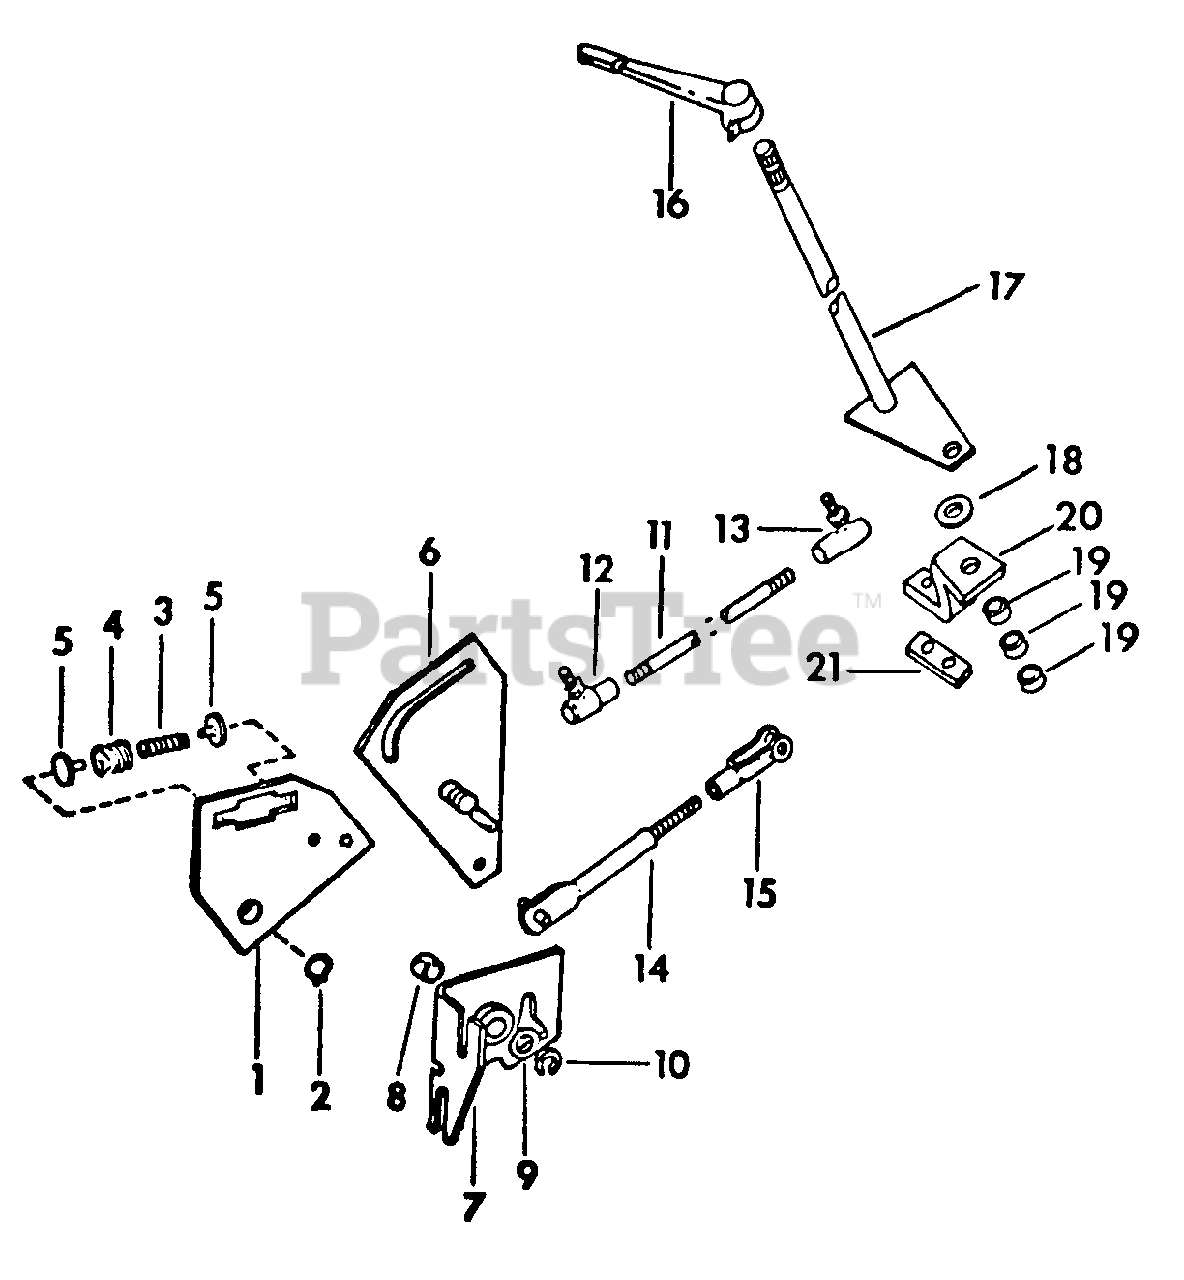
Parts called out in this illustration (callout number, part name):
1	Plate Assy, Damper Spring
2	Ring, Damper Plate Retaining
3	Spring, Damper Light
4	Spring, Damper Heavy
5	Pin, Damper Spring Guide
6	Cam Assy, Control
7	Bracket Assy, Cam Pivot
8	Bushing, Cam Pivot
9	Washer, Cam Retaining
10	Ring, Cam Retaining
11	Stud, Connecting
12	Joint, 5/16-24 X 1-1/2 C-Z RH Thd Ball
13	Joint, 5/16-24 C-Z Ball
14	Rod Assy, Control
15	Clevis, 5/16 Adj Rod End Pin
16	Handle, Speed Control
17	Shaft Assy, Control
18	Disc, Friction
19	Washer, Belleville Spring
20	Support, Control Rod
21	Shim, Control Support
